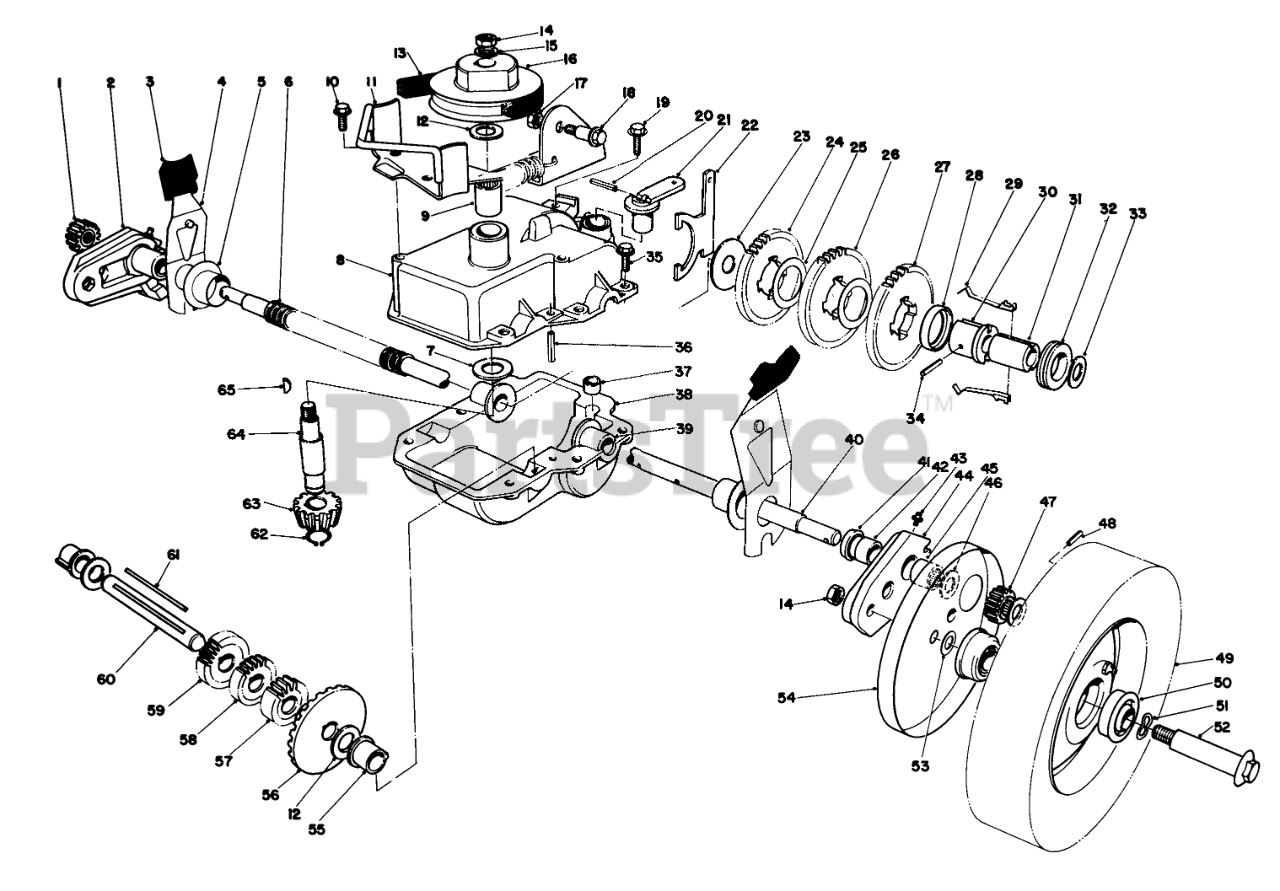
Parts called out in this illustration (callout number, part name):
1	Pinion Gear
2	Pivot Arm R.H. (Incl. Ref. #41-43 & 45)
3	KNOB-ARM
4	SPRING ARM ASM SP
5	CAP-END
6	CONDUIT-CONVOLUTED, SPLIT
7	Thrust Washer
8	Case-Upper
9	Bearing
10	SCREW
11	Belt Guide Bracket
12	WASHER-THRUST
13	V-BELT
14	Nut
15	WASHER-FLAT
16	Pulley
17	NUT-LOCK, CONE
18	SHOULDER BOLT
19	SCREW-HWHTF
20	PIN-COIL
21	LEVER-SHIFT
22	Shift Yoke
23	WASHER
24	Gear 35 Tooth
25	Washer
26	Gear 37 Tooth
27	GEAR-42T
28	KEY RETAINER
29	Key
30	Body-Sleeve
31	SLEEVE
32	COLLAR-SHIFT
33	WASHER-PLAIN
34	PIN-SPRING
35	SCREW-HWH, THREAD ROLL
36	ROLL PIN 3/16 X 1 IN
37	BUSHING-YOKE
38	LOWER GEAR CASE CAST
39	Bushing
40	OUTPUT SHAFT
41	Seal
42	Bushing
43	FITTING-GREASE
44	Pivot Arm L.H. (Incl. Ref. #41-43 & 45)
45	Needle Baring
46	WASHER
47	Pinion Gear
48	Pin
49	Wheel & Tire Assembly (Incl. Ref. #50)
50	BEARING-BALL
51	SPRING WASHER
52	WHEEL BOLT
53	WASHER
54	Cover-Wheel
55	Botching Shaft
56	BEVEL GEAR
57	14 T GEAR
58	Gear 19 Tooth
59	Gear 21 Tooth
60	Sort Shaft
61	Key Square
62	RING-RETAINING
63	PINION-BEVEL
64	INPUT SHAFT
65	KEY-WOODRUFF
